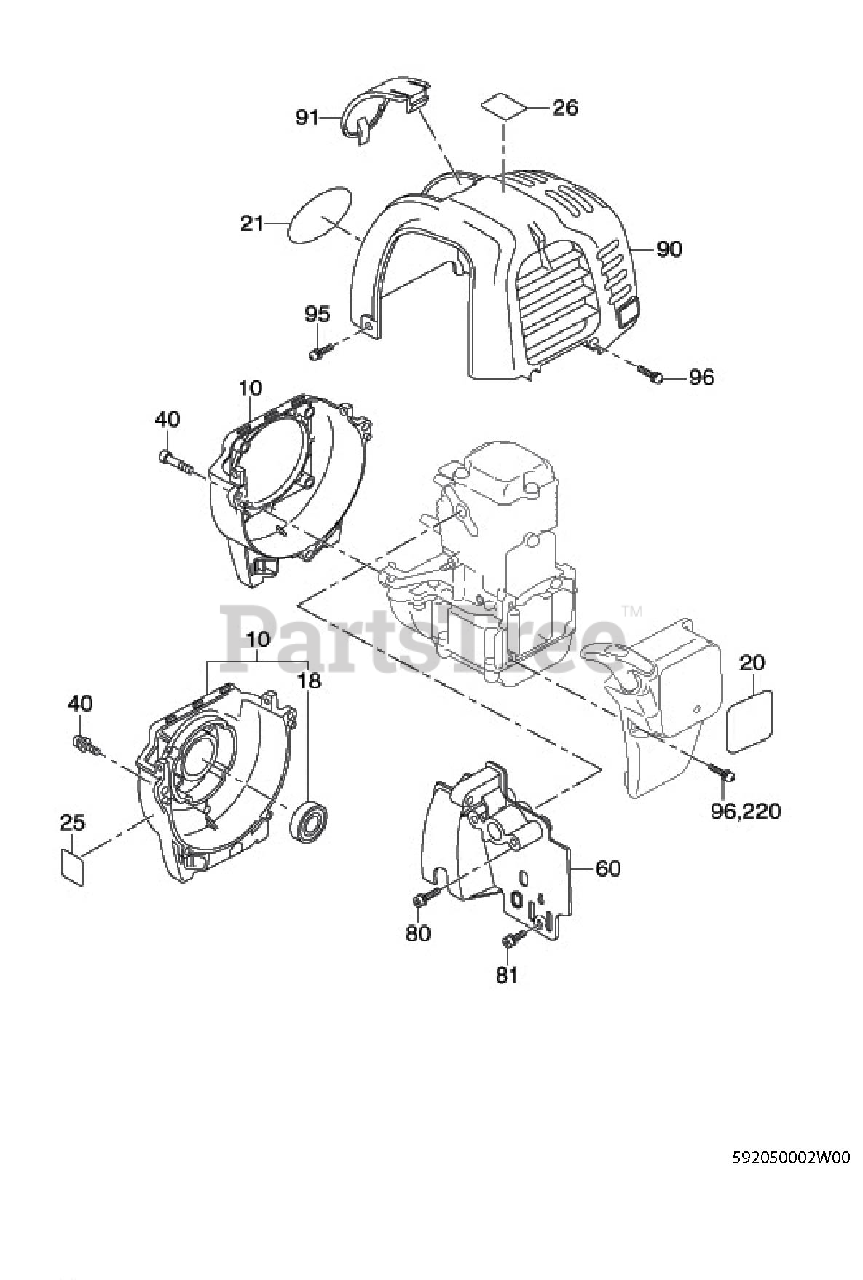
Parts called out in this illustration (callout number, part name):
10	HOUSING,BLOWER
18	BALL BEARING
20	LABEL,MODEL
21	LABEL,TRADE MARK
25	LABEL, CAUTION
26	LABEL, CAUTION
40	H. S. H. BOLT
60	INSULATOR CP
80	H. S. H. BOLT
81	SOCKET HEAD BOLT
90	COVER,CYLINDER
91	COVER,PLUG
95	P. H. SCREW
96	SCREW
220	SCREW
